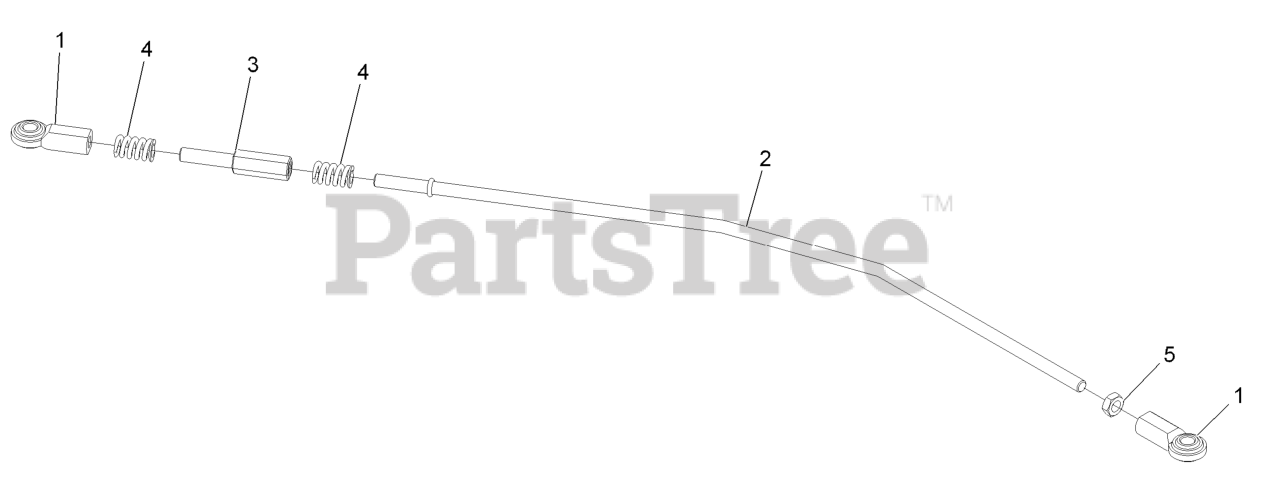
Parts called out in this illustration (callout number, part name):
1	JOINT-BALL, END
2	LINK-LOWER,MOTION CONTROL
3	ROD-ADJUSTMENT
4	SPRING-COMPRESSION
5	NUT-HJ
